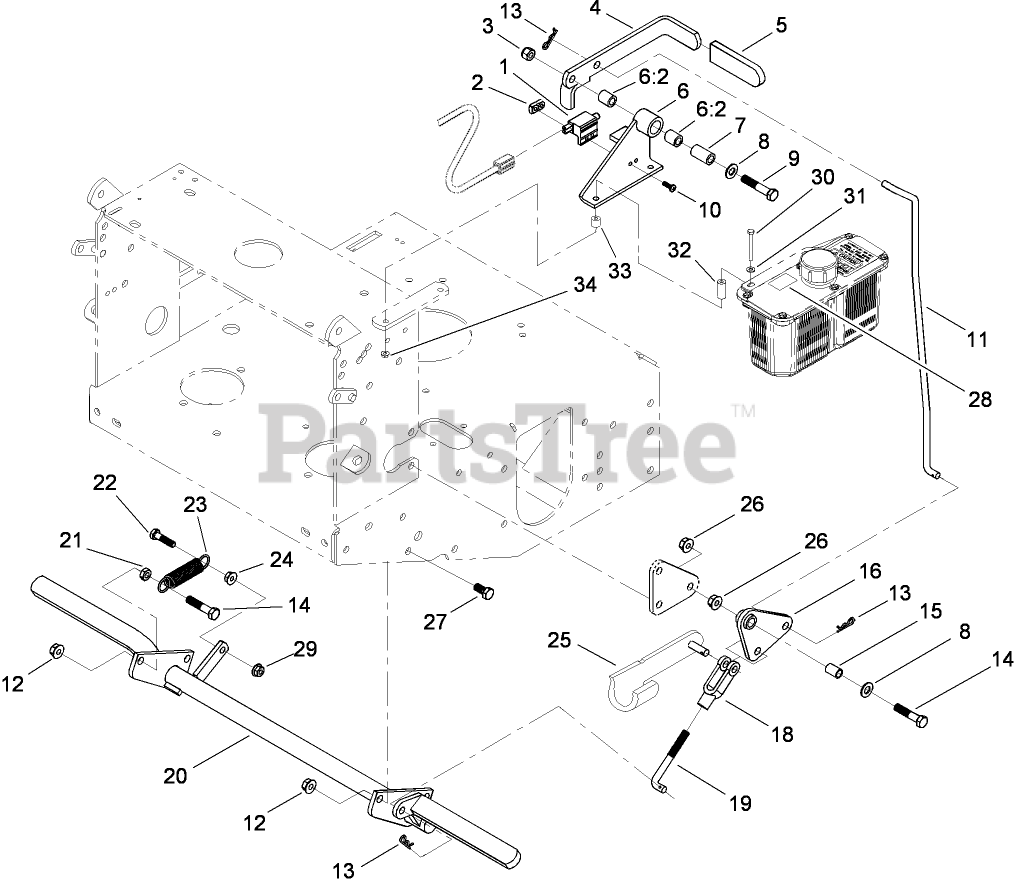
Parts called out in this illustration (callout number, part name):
1	SWITCH-OPEN, NORMALLY
2	PLATE-TAPPED
3	NUT-LOCK, NI
4	Lever-Parkbrake
5	GRIP-LEVER
6	Bracket ASM
6:2	SLEEVE-BUSHING
7	Bushing-Pivot
8	WASHER-FLAT
9	SCREW-HH
10	SCREW-PPH
11	Linkage-Upper
12	NUT-LOCK, NI
13	PIN-COTTER
14	SCREW-HH
15	Bushing-Plastic
16	Bellcrank ASM
18	YOKE-LINKAGE, BRAKE
19	Linkage-Lower
20	BRAKE ASM
21	NUT-JAM
22	SCREW-HH
23	SPRING-IDLER
24	NUT-HF
25	Pin-Spring, Clevis
26	NUT-HF
27	SCREW-HH
28	DECAL-BRAKE, PARK
29	NUT-LOCK, NI
30	SCREW-HH
31	WASHER-FLAT
32	Spacer
33	SPACER
34	NUT-HF
